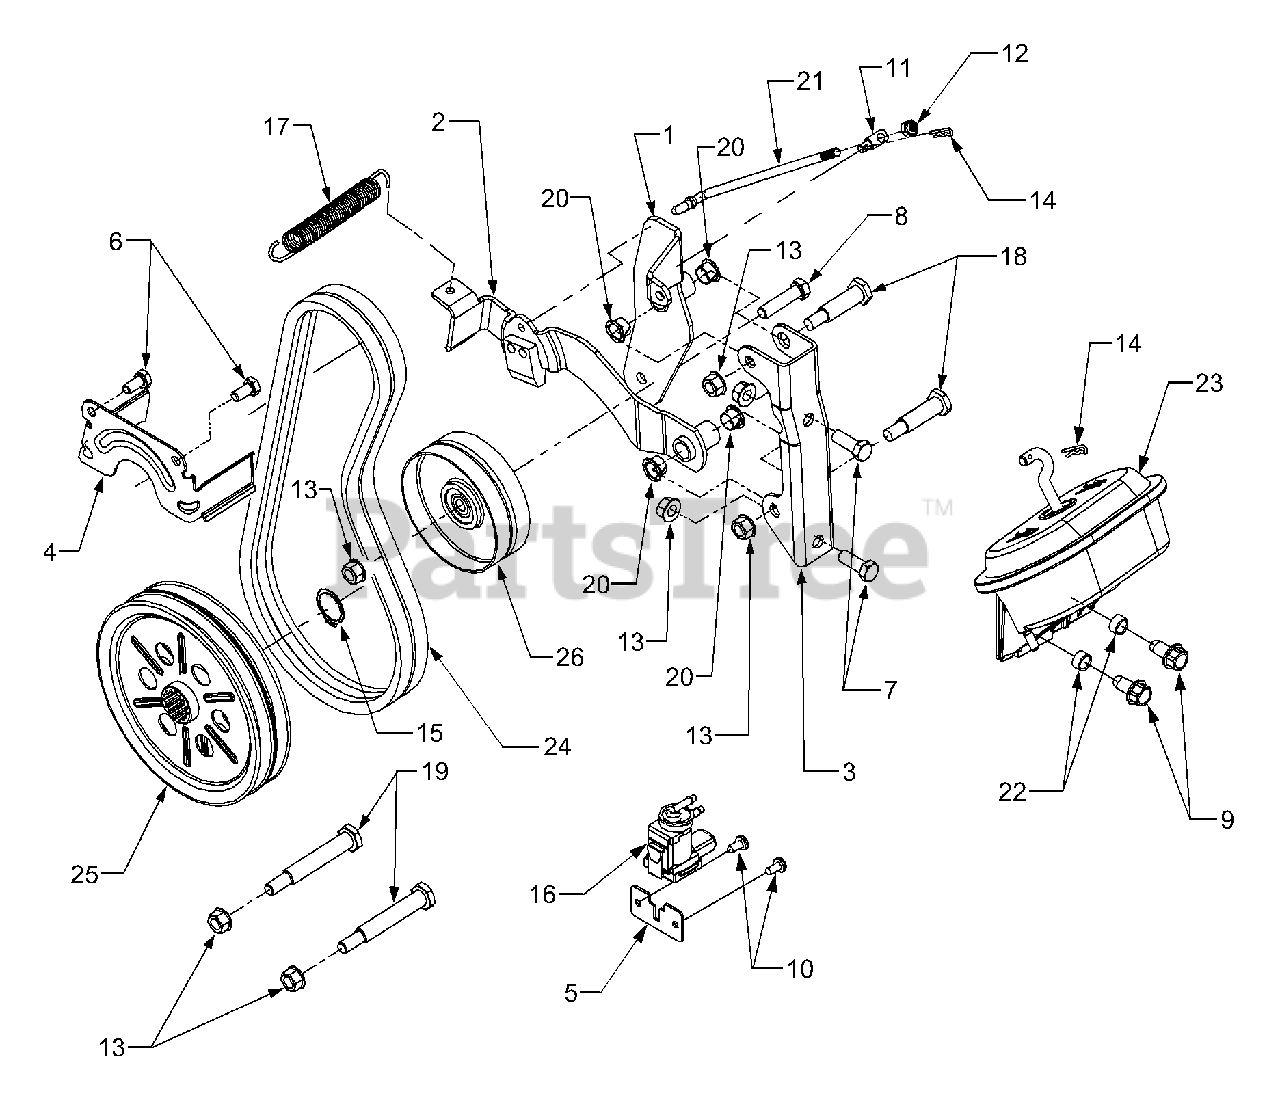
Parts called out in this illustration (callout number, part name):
1	Bracket, Idler
2	Bracket Assembly, Brake
3	Bracket, PTO Mounting
5	Bracket, Solenoid Mounting
6	Screw, Hex Cap 5/16-24 x .625 GR5
7	Screw, Hex Cap 3/8-16 x 1.0 GR5
8	Screw, Hex Cap 3/8-16 x 1.5 GR5
9	Screw, Hex Wash. Hd. Tapp 3/8-16 x .75
10	Screw, Phil. Hd. Tapp #12-14 x .5
11	Ferrule, Brake Adjustment
12	Nut, Hex Insert Lock, 1/4-20
13	Nut, Flange Lock, 3/8-16
14	Pin, Internal Cotter
15	Snap Ring, 1.0 Dia Shaft
16	Solenoid, Kit Vacuum Actuator
17	Spring, Extension, .530 x 4.74
18	Shoulder Screw, .498 x 1.45
19	Shoulder Screw
20	Bearing, Nylon Flange
21	Rod, PTO Brake
22	Spacer, .380 x .5 x .265
23	Vacuum Actuator
24	V-Belt, A-Section x 37.63 (Set of two belts)
25	Pulley, PTO Drive. 6.75-Double
26	Pulley, Flat Idler, 4.0
